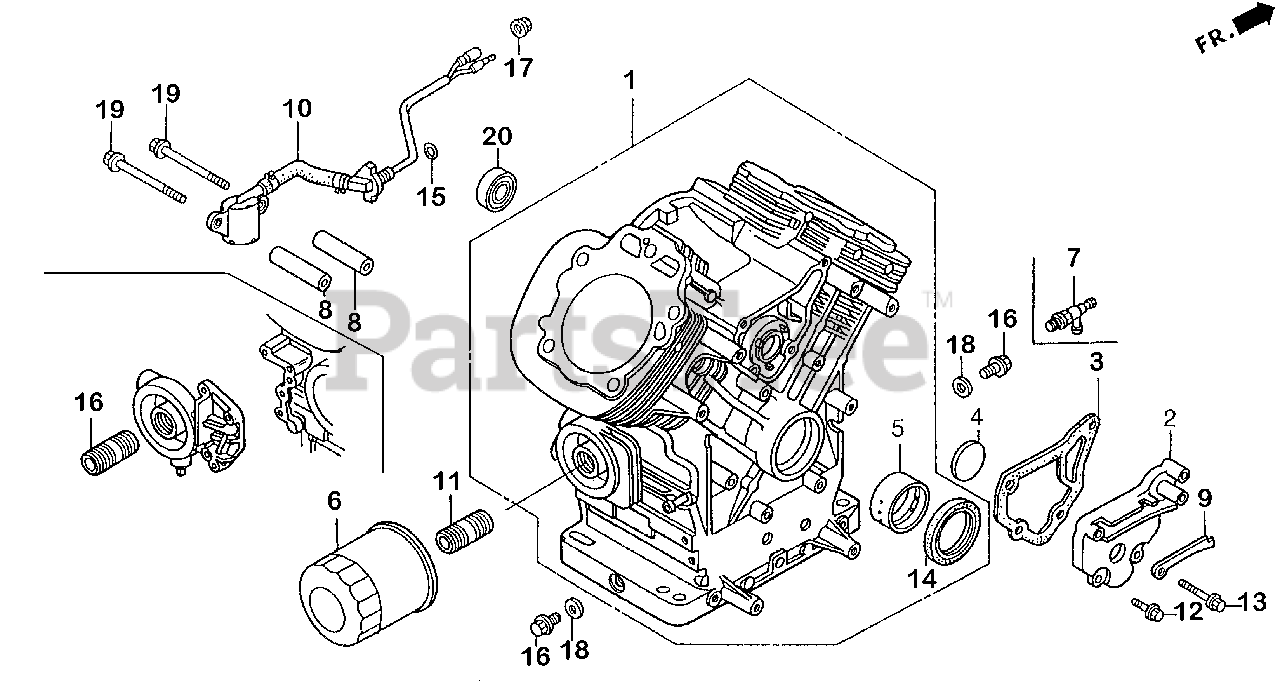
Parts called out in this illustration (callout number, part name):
1	CYLINDER ASSY.
2	COVER, BREATHER
3	GASKET, BREATHER COVER
4	VALVE, BREATHER
5	BEARING A, MAIN (BLUE) (TO SELECT CORRECT BEARING, SEE THE SERVICE MANUAL.)
5	BEARING B, MAIN (BLACK) (TO SELECT CORRECT BEARING, SEE THE SERVICE MANUAL.)
5	BEARING C, MAIN (BROWN) (TO SELECT CORRECT BEARING, SEE THE SERVICE MANUAL.)
6	FILTER, OIL (FILTECH TOYO ROKI) (SOLD INDIVIDUALLY)
6	FILTER, OIL
6	FILTER, OIL (SOLD IN MULTIPLES OF 30)
6	FILTER, OIL (Honda Code 6836290). (SOLD INDIVIDUALLY)
7	VALVE, DRAIN (14X1.5)
8	COLLAR, FILTER SETTING
9	CLAMP, WIRE
10	SWITCH ASSY., OIL LEVEL
11	HOLDER, OIL FILTER
12	BOLT, FLANGE (6X16)
13	BOLT, FLANGE (6X32)
14	OIL SEAL (38X58X11)
15	O-RING (14MM) (ARAI) Use up to Engine SN 2949254.
16	BOLT, DRAIN PLUG (14MM)
17	NUT, FLANGE (10MM)
18	WASHER, DRAIN PLUG (14MM)
19	BOLT, FLANGE (6X75)
20	BEARING, RADIAL BALL (6003)
